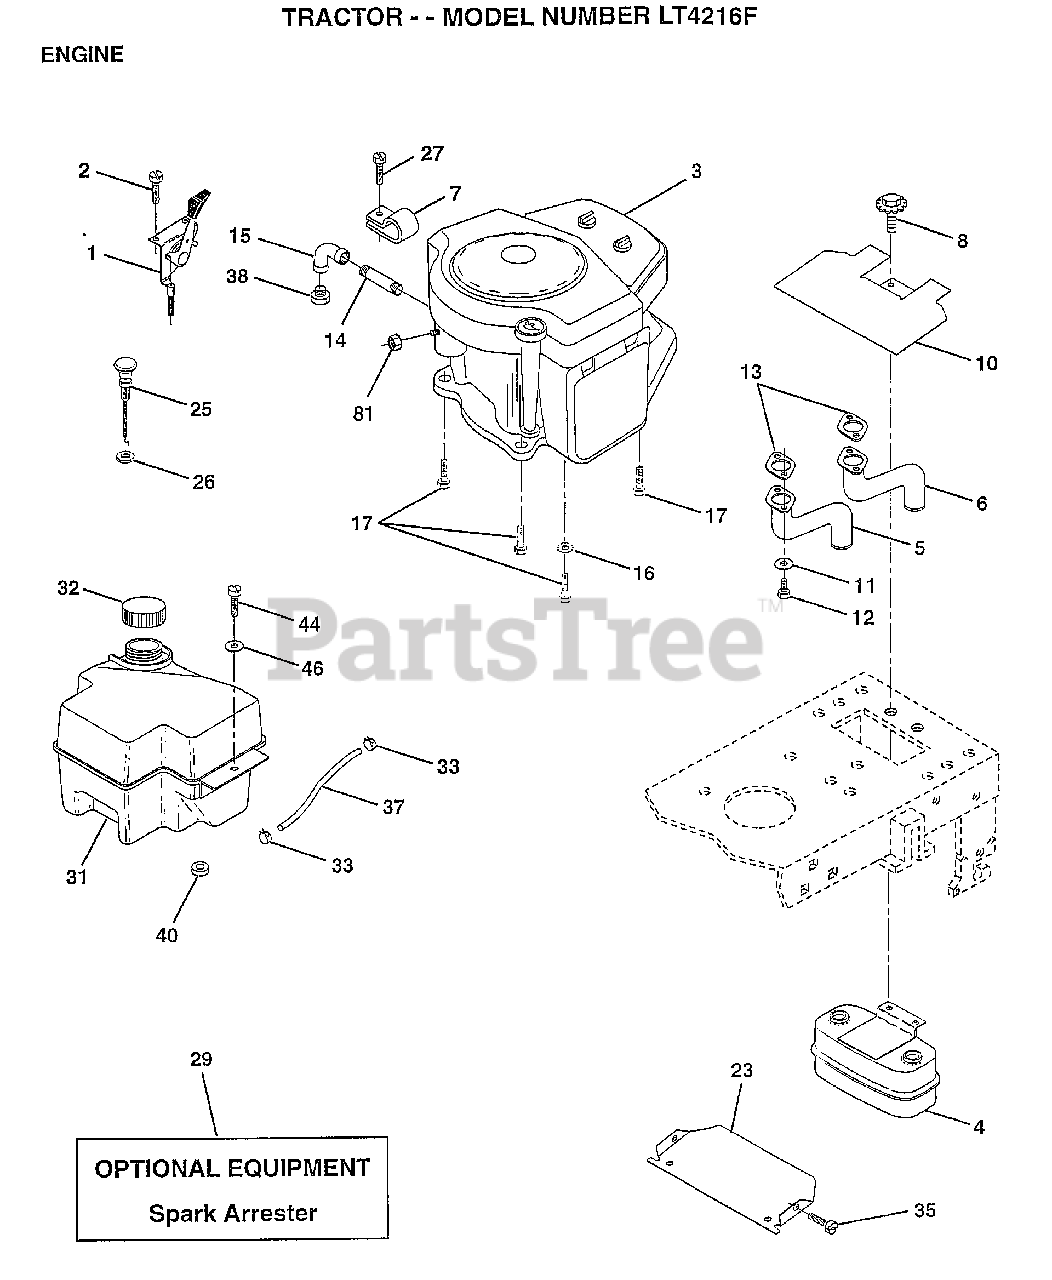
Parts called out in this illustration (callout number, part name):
1	CONTROL THRT 35.5
2	SCREW LT
4	MUFFLER.TW.LOTONE
5	EXHAUST.B&S.18.LH
6	EXHAUST.B&S.18.RH
7	CLAMP.TUBE.DBL.EN
8	BOLT.5/16-18.UNC
10	SHIELD.HEAT.
13	GASKET MUFFLER
14	PIPE NIPPLE LT
15	ELBOW
16	LOCKWASHER
17	SCREW LT
24	SCREW
25	CONTROL.CHOKE.37
26	"NUT,KEPS 3/8-24IM"
27	SCREW.10-24X1/2
32	CAP ASM FUEL
33	HOSE CLAMP
35	SCREW
37	LINE FUEL
44	SCREW HEX CRT
46	WASHER
81	NUT
